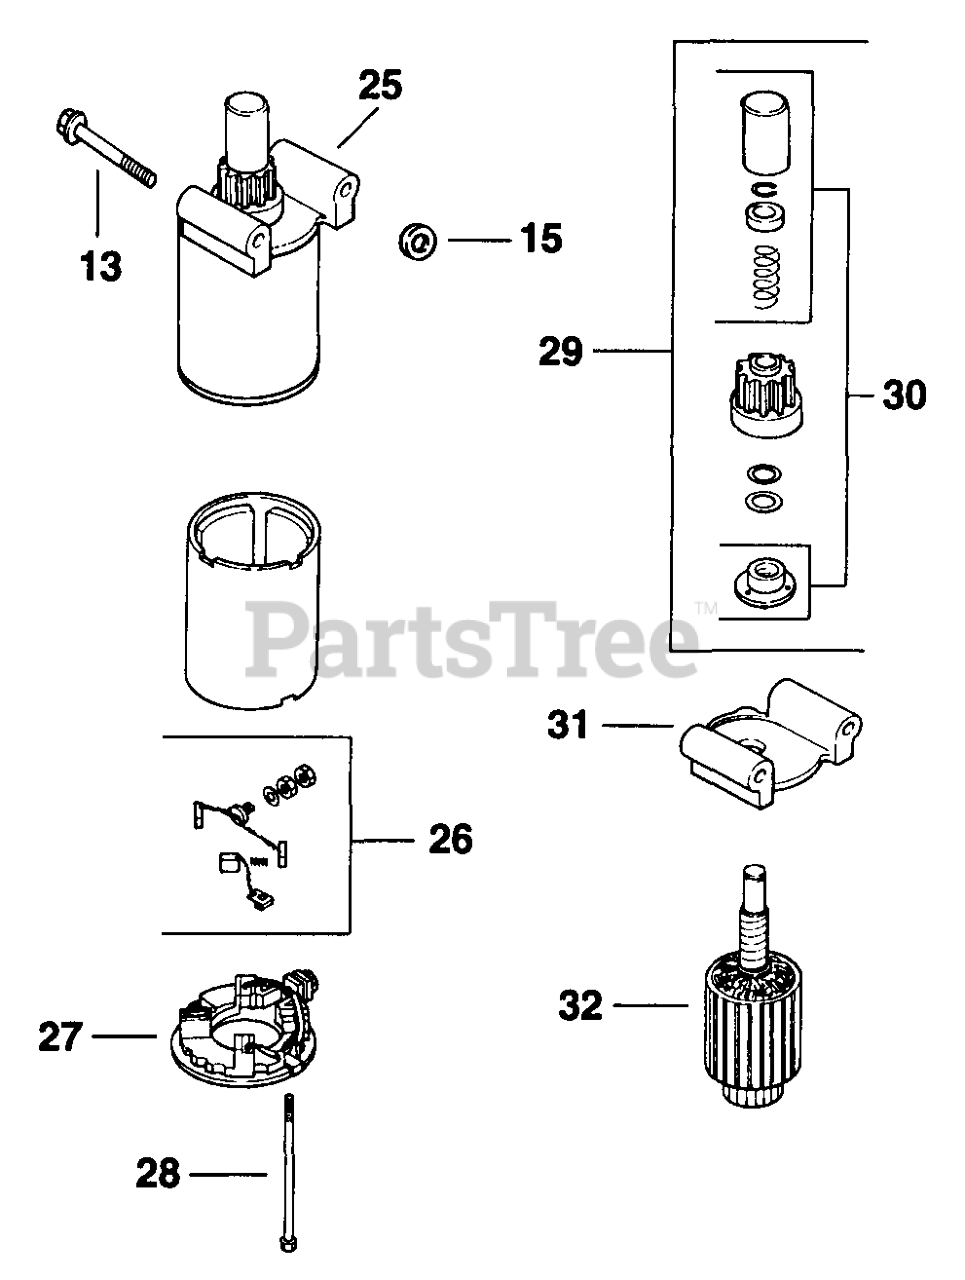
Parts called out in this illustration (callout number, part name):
26	Kit, Brush & Spring
27	Cap, Commutator End
28	Screw, Hex. Flange - Type "B" 10-16x4-3/16"
29	Kit, Drive
30	Kit, Drive Parts
31	Cap, Drive End
32	Armature
